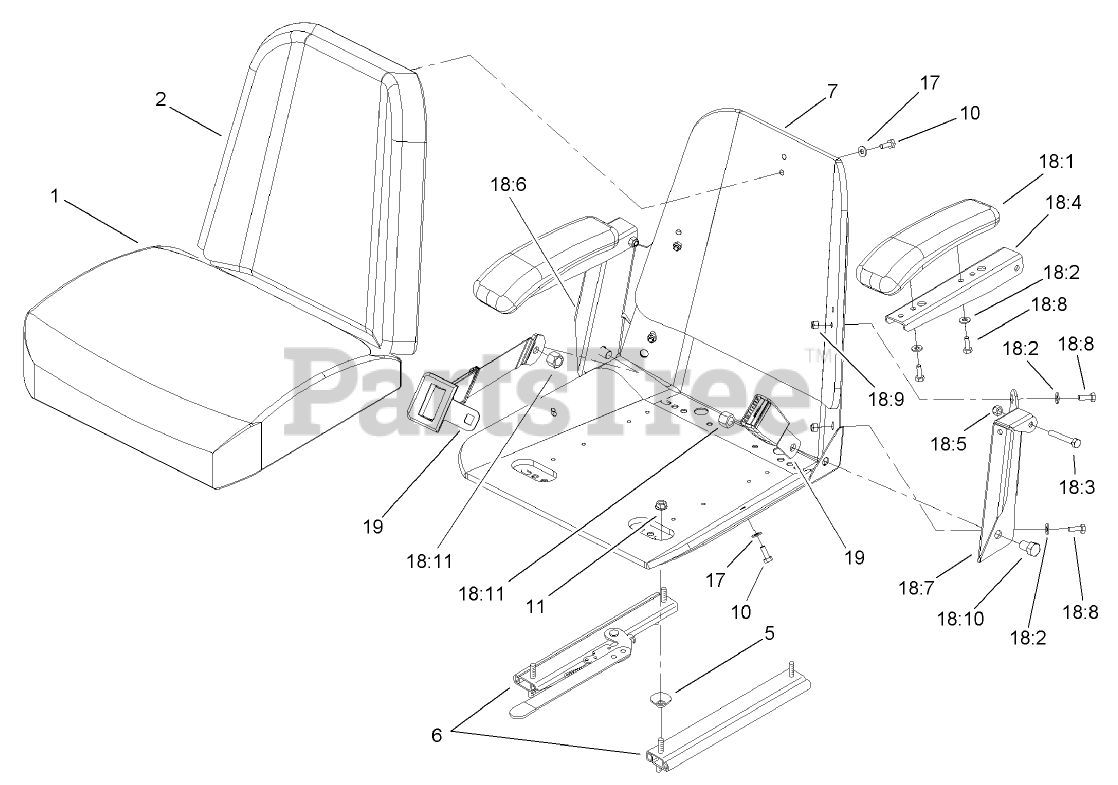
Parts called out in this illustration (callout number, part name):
1	CUSHION-SEAT, BOTTOM
2	CUSHION-SEAT, BACK
5	SPACER-TRACK
6	TRACK-SEAT
7	FRAME-SEAT
10	SCREW-HH
11	NUT-HF
17	WASHER-FLAT
18	ARMREST KIT
18:1	CUSHION-ARMREST
18:2	WASHER-FLAT
18:3	SCREW-HH
18:4	CHANNEL-ARMREST
18:5	NUT-HEX, SIDE DEFORM
18:6	Bracket-Armrest, RH
18:7	Bracket-Armrest, LH
18:8	SCREW-HH
18:9	NUT-LOCK, NI
18:10	SCREW-HH
18:11	NUT-LOCK, NI
19	Belt-Seat
